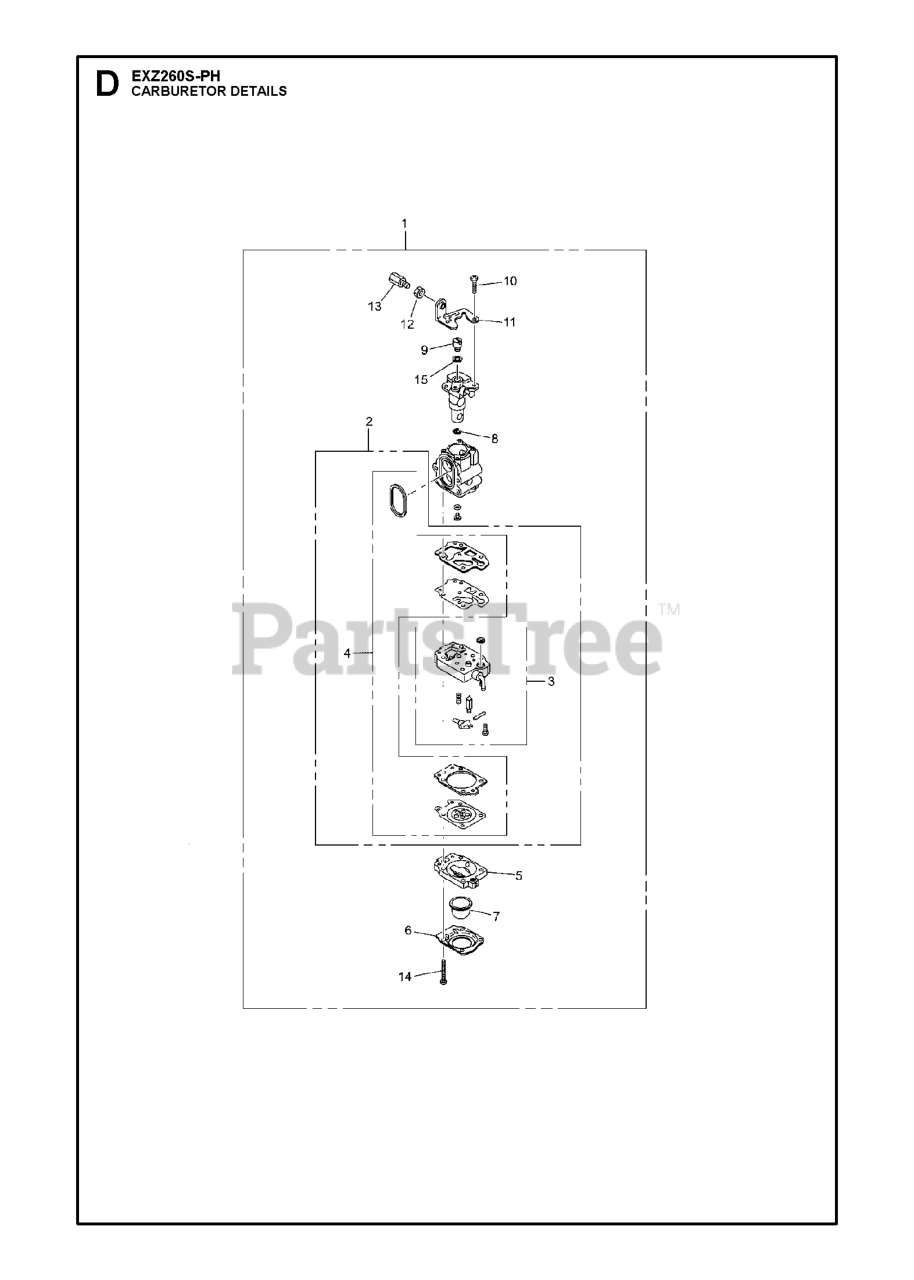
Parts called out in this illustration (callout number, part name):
1	CARBURETOR ASSY
2	REBUILD KIT
3	CARBURETOR BODY
4	GASKET KIT
6	1OVER
8	RING
9	SWIVEL
10	SCREW
11	BRACKET
12	NUT
13	ADJUSTER
15	WASHER
